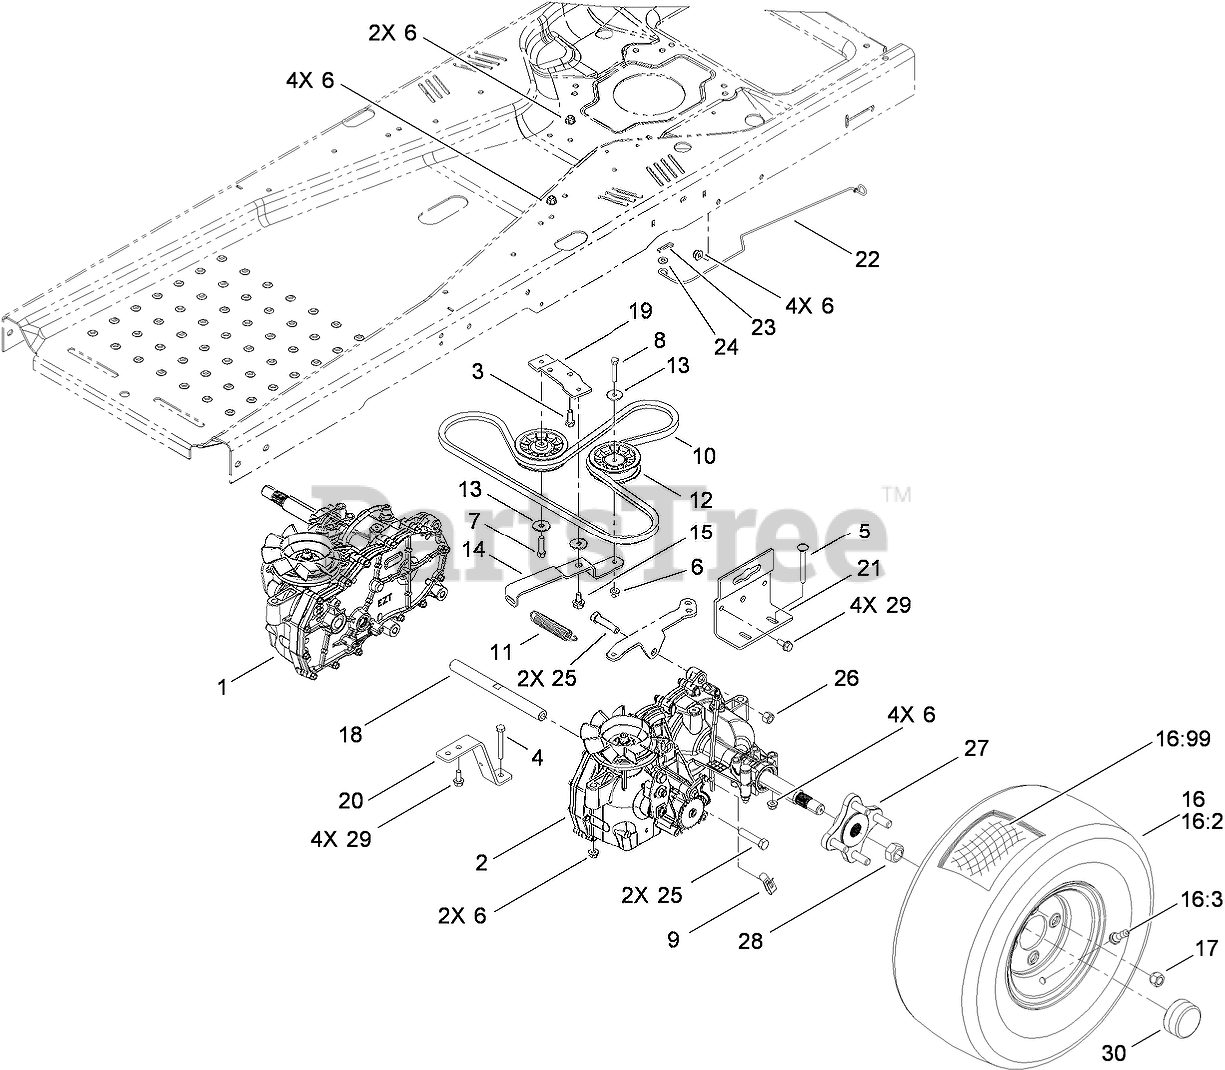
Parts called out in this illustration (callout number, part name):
1	HYDRO-RH
2	HYDRO-LH
3	SCREW-HH
4	SCREW-HH
5	SCREW-CARR
6	NUT-HF, NI
7	SCREW-HH
8	SCREW-HH
9	CLIP-SPRING
10	V-BELT
11	SPRING-IDLER
12	PULLEY-IDLER
13	WASHER-PIVOT
14	ARM-IDLER
15	BOLT-SHOULDER
16	WHEEL AND TIRE ASM
16:2	TIRE
16:3	STEM-VALVE
16:99	TUBE-TIRE
17	NUT-LUG
18	SHAFT-CROSS
19	PLATE-PIVOT
20	STRAP-TORQUE
21	SUPPORT-HYDRO
22	ROD-BYPASS
23	PIN-COTTER
24	WASHER-FLAT
25	SCREW-HH
26	NUT-LOCK, NI
27	HUB ASM
28	NUT-LOCK
29	SCREW-HHF
30	COVER-NUT, AXLE
